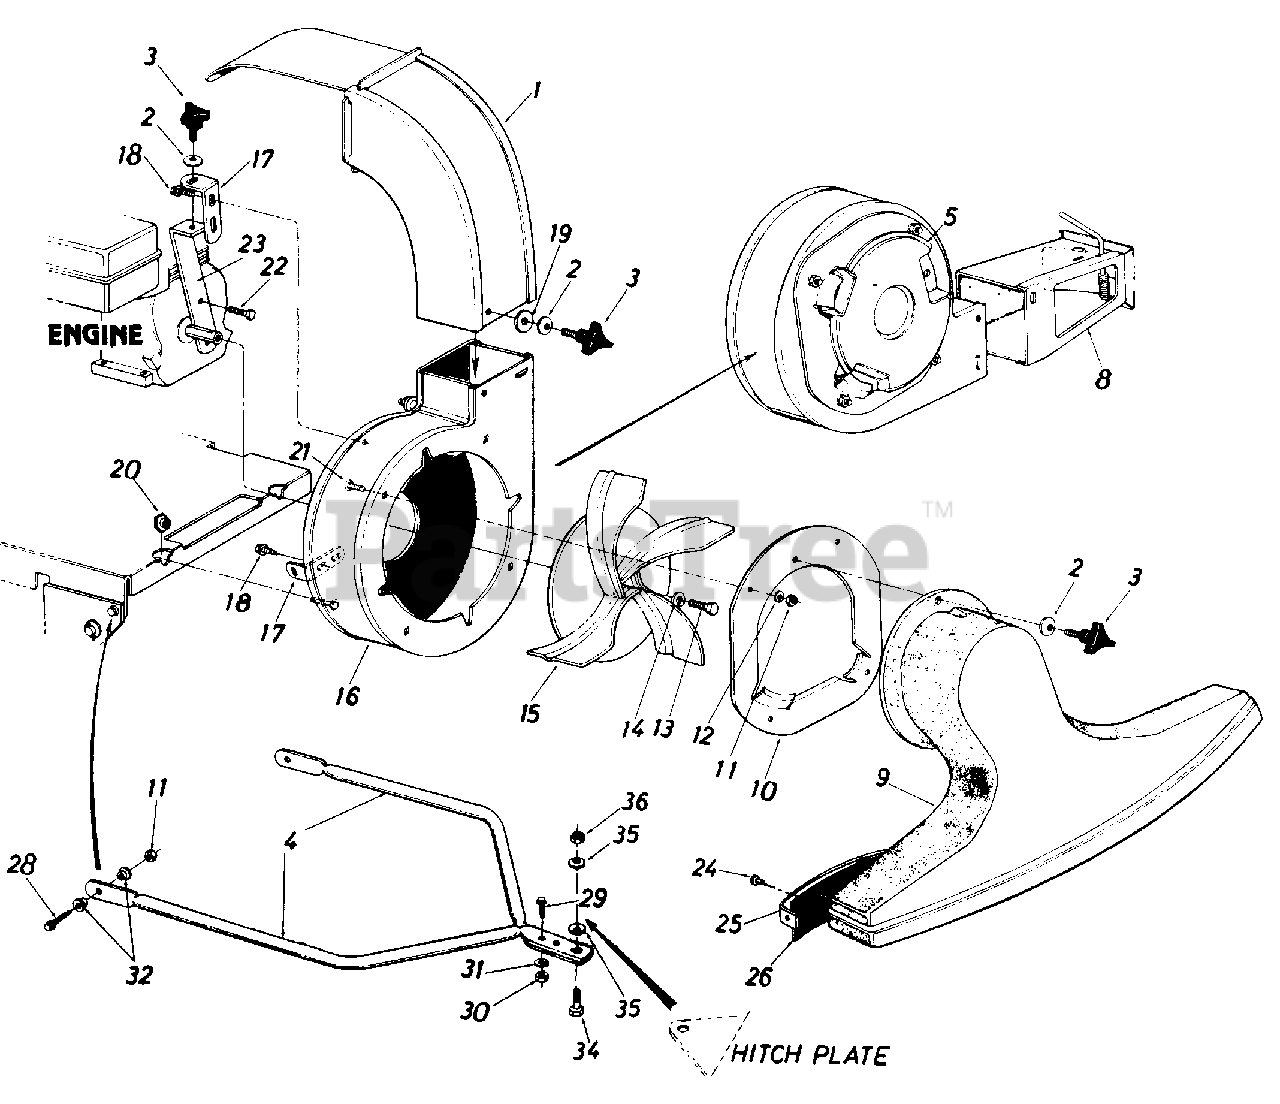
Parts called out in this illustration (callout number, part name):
3	3-Arm Thumb Scr. 5/16-18 x .75" Lg.
10	Nozzle Plate Ass'y.
11	Hex Nut 5/16-18 Thd.
12	L.-Wash. 5/16" I.D.
13	Hex Bolt 3/8-24 x 1.25" Lg.
14	L.-Wash. 3/8" I.D. H.D.
15	Air Vane Plate Ass y.
16	Blower Housing Complete
19	Fl.-Wash. 5/16" I.D.
20	Hex Shoulder Nut .50 I.D.
21	Carriage Bolt 5/16-18 x .62" Lg.
22	Hex Locking Bolt 5/16-24 x .75" Lg.
28	Hex Bolt 5/16-18 x 1.00" Lg.*
29	Truss Mach. Scr. 1/4-20 x .75" Lg.*
30	Hex Nut 1/4-20 Thd.*
31	L. Wash. 1/4" 1. D.*
32	Shoulder Spacer
34	Shld. Bolt .496 Dia.
35	Belleville Wash. .39 I.D. x 1.12 O.D.
36	Hex Jam L-Nut 3/8-16 Thd.
